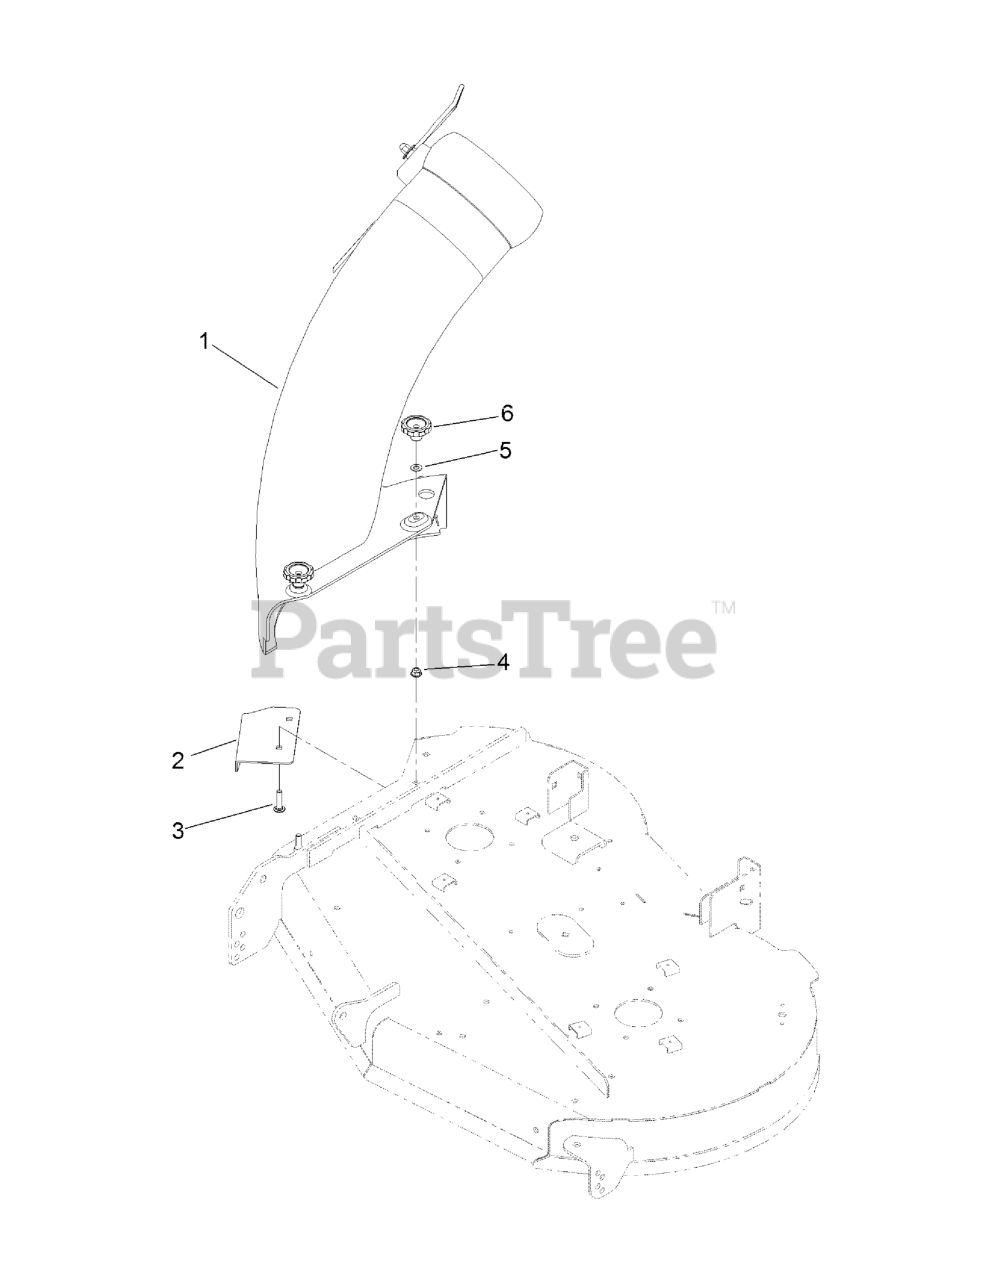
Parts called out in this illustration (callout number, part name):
1	CHUTE ASM
2	BAFFLE-CUTOFF
3	SCREW-CARR
4	NUT-HF, NI
5	WASHER-PLAIN
